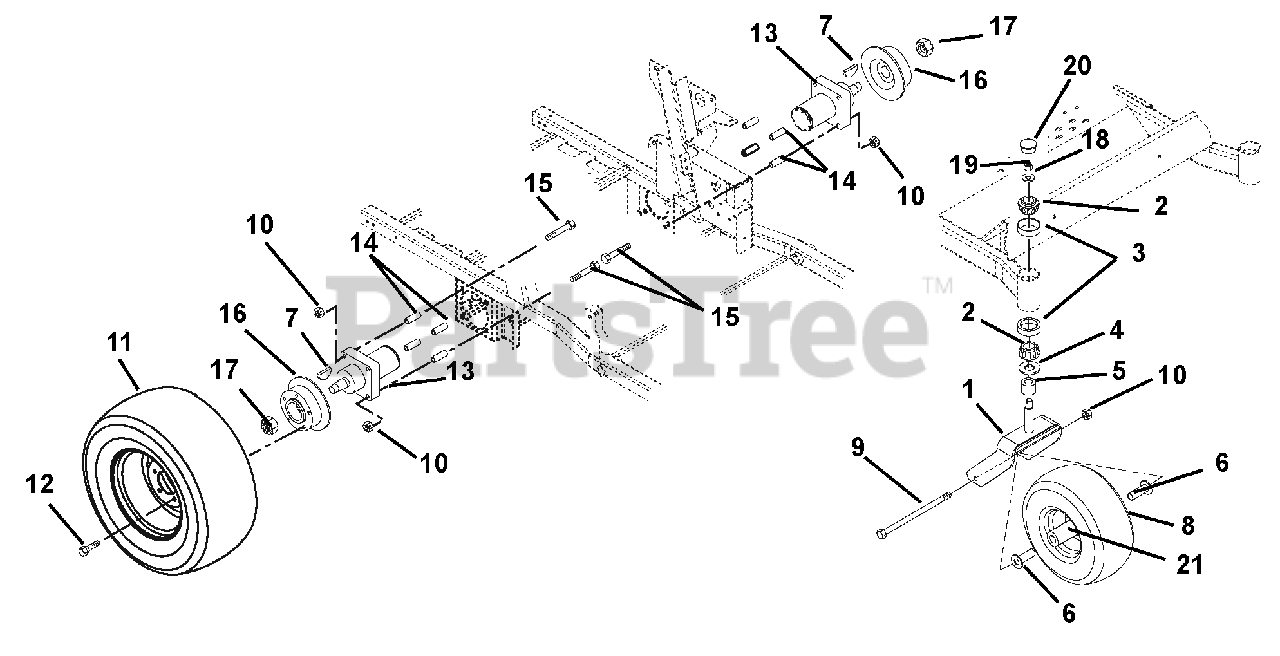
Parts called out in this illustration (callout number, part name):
1	FORK - BLACK
2	BRG, CONE W/ GREASE
3	BRG-CUP1.980X.420
4	BEARING SEAL 1.5 X 2 X .18
5	SPACER 1.005X1.5075X.375
6	SPACER, FRONT WHEEL
7	KEY-WDRF .31X1.00 SFT #B
8	TIRE/WHEEL ASSY, 15X6.00-6
9	@BLT-HEX .50-13X9.00 GR5 YWZC
10	@NUT-LK-TOP-FLG .50-13 YWZC
11	TIRE/WHEEL ASSY, 23X10.00-12
12	BLT, LUG .50-20 X 1.38
13	MOTOR, WHEEL HGM 15E (CW)
14	BSHG-SLV .513X.748X2.129
15	@BLT-HEX .50-13X5.00 GR8 YWZC
16	HUB & DISK (PARK) 8" 1/2 HOLE
17	NUT-LK-JAM-PTCH 1.00-20
18	@WSHR-FL-STL.812X1.50X.135YWZC
19	NUT-JAM CTRLK .75-16 YWZC
20	CAP, DUST
21	BRG, 25MM ID X 52MM OD X 15MM
